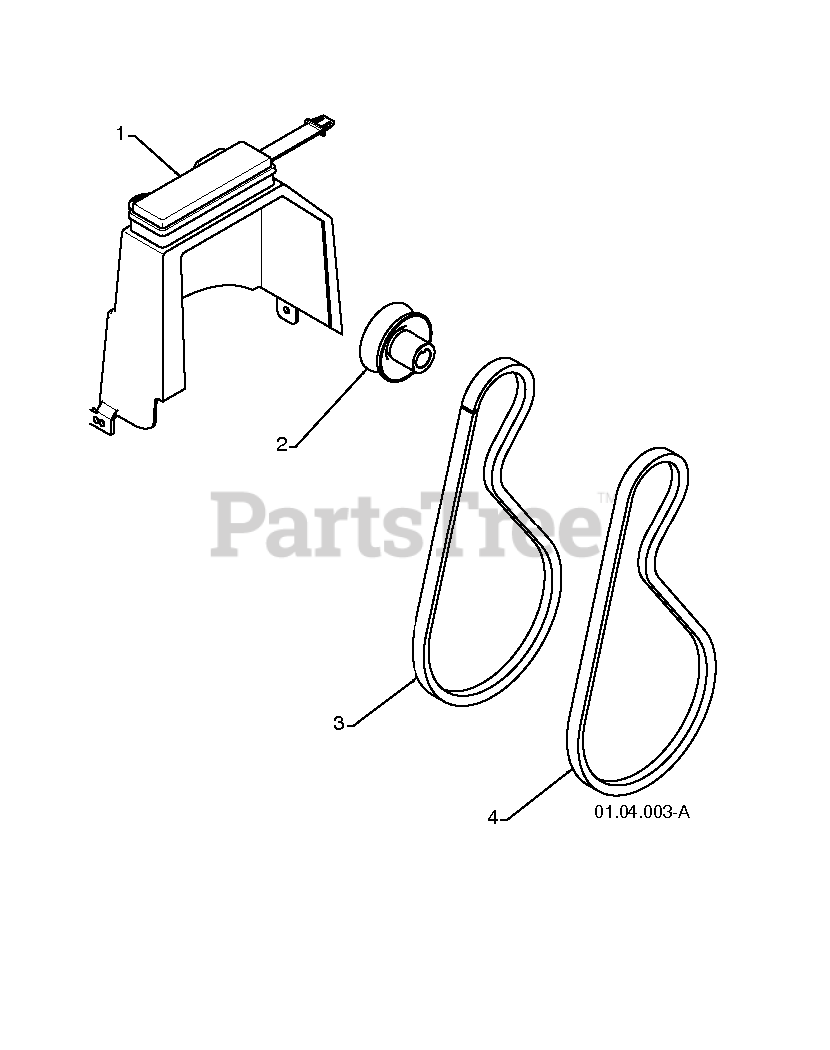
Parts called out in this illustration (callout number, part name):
1	COVER.ASM.BELT/STORAGE
2	PULLEY, ENGINE IMPELLER DRIVE
3	V-BELT TRACTION 34.25
4	BELT.V.IMPELLER
